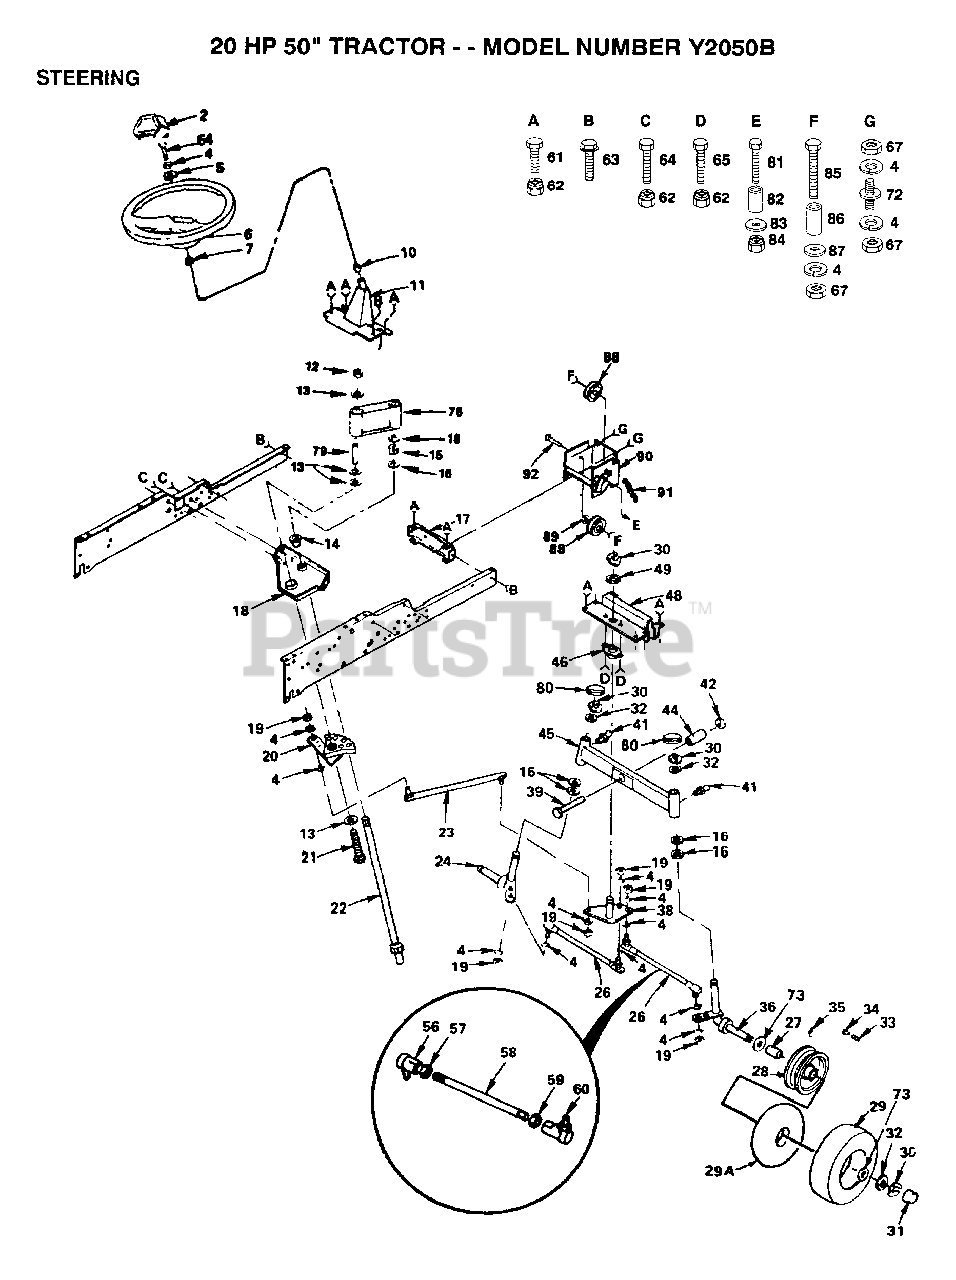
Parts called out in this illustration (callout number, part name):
2	INSERT STEERING
4	LOCKWASHER
5	WASHER T
7	ADAPTER LT
10	"T, BEARING"
11	SUPPORT ASSY T
12	NUT LTV
13	WASHER GT
14	"FLANGE GT, BEAR."
15	KLIP RING
16	WASHER .T
17	FRAME BRACKET GT
20	SECTOR T
21	BOLT T
22	SHAFT STEERING GT
23	LINK.DRAG.T
24	SPINDLE ASSY T
26	TIE ROD T
27	"FLANGE, BEARING"
29A	TUBE.16X6.5/7.5-8
30	RING
31	HUB CAP
32	WASHER
33	VALVE CAP
34	VALVE STEM LT
35	FITTING LT
36	SPINDLE RH T
38	"T, BELLCRANK"
39	BOLT
41	ZERK M
42	LOCKNUT M
44	SPACER BEARING
48	AXLE BRACKET T
49	WASHER
56	JOINT.LH
57	NUT
59	NUT
60	JOINT.RH
63	SCREW
64	BOLT
65	BOLT
67	NUT.HEX.3/8-16UNC
73	WASHER
76	COLLAR
79	TUBE T
80	CAP
82	SPLIT SPACER YTV
83	WASHER
85	BOLT
86	BUSHING LT
87	WASHER
88	IDLER-INSIDE T
89	WASHER T
90	IDLER BRKT T
91	SPRING
